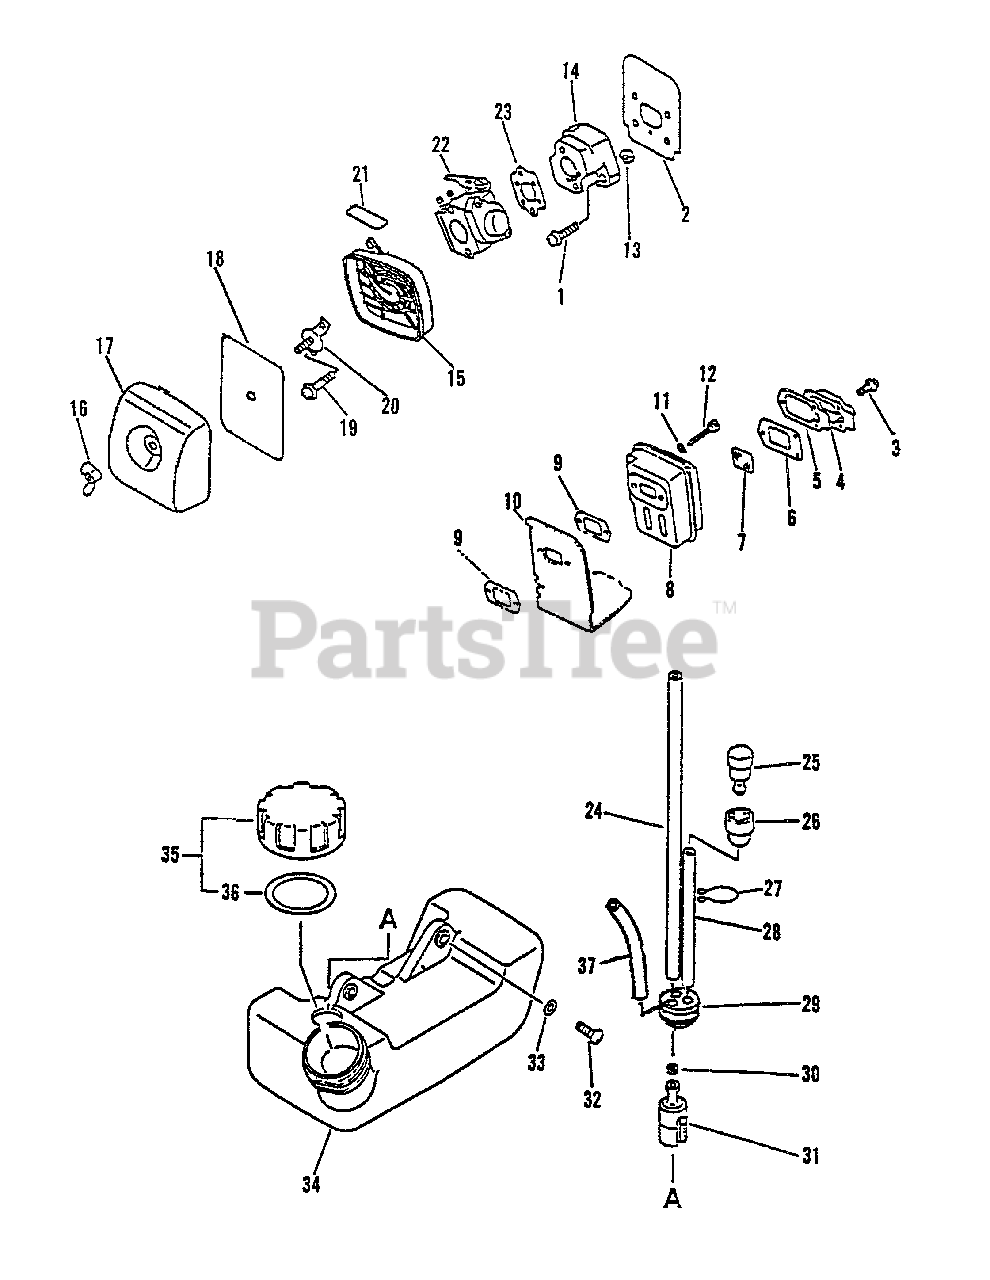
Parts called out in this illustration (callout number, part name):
1	SCREW 5×22
2	GASKET, INTAKE
3	SCREW 4×10
4	GUIDE, EXHAUST - INNER
5	GUIDE, EXHAUST
6	GASKET, EXHAUST
7	SCREEN, SPARK ARRESTER
8	MUFFLER ASSY
9	GASKET, EXHAUST
10	COVER, MUFFLER
11	WASHER, FLAT 5.5×10×0.8
12	BOLT 5×55
13	NUT M5
14	INSULATOR, INTAKE
15	AIR FILTER CASE ASSY
16	WINGNUT - 6
17	COVER, AIR FILTER
18	FILTER, AIR
19	SCREW 5×65
20	PLATE, PREVENT
21	LABEL, CHOKE
22	CARBURETOR - C1U-K32
23	GASKET, INTAKE
24	PIPE, FUEL 3x-5x-180
25	VENT ASSY
26	HOLDER, VENT
27	CLIP, TUBE
28	PIPE, FUEL 3x-5x-70 BLACK
29	GROMMET, FUEL
30	CLIP 6 MM
31	FILTER, FUEL
32	SCREW 5×16
33	WASHER 5.5×12×0.8
34	TANK, FUEL
35	CAP ASSY
36	GASKET, FUEL CAP
37	PIPE, FUEL RETURN 3×6×90 MM CLEAR
